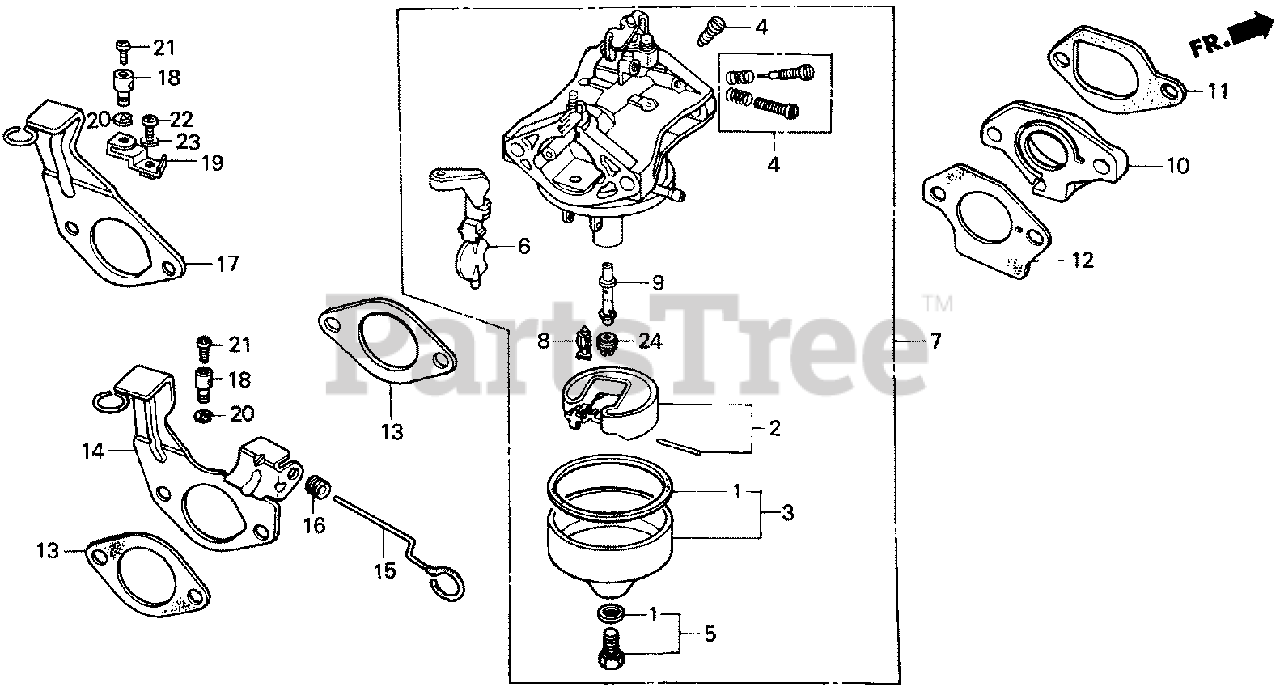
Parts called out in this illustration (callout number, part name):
1	GASKET SET
3	CHAMBER SET, FLOAT
4	SCREW SET A
4	SCREW SET A (NOT AVAILABLE)
5	SCREW SET B
7	CARBURETOR ASSY.
7	CARBURETOR ASSY. (BB33D D)
8	VALVE, FLOAT
9	NOZZLE, MAIN
10	INSULATOR, CARBURETOR
11	GASKET, INSULATOR
12	GASKET, CARBURETOR
13	GASKET, AIR CLEANER
14	STAY, CHOKE CONTROL
15	ROD, CHOKE CONTROL
16	GROMMET, CHOKE ROD
18	HOLDER, CABLE
20	CIRCLIP (5MM)
21	SCREW, PAN (4X8)
24	JET, MAIN (#85)
24	JET, MAIN (#88)
24	JET, MAIN (#90)
